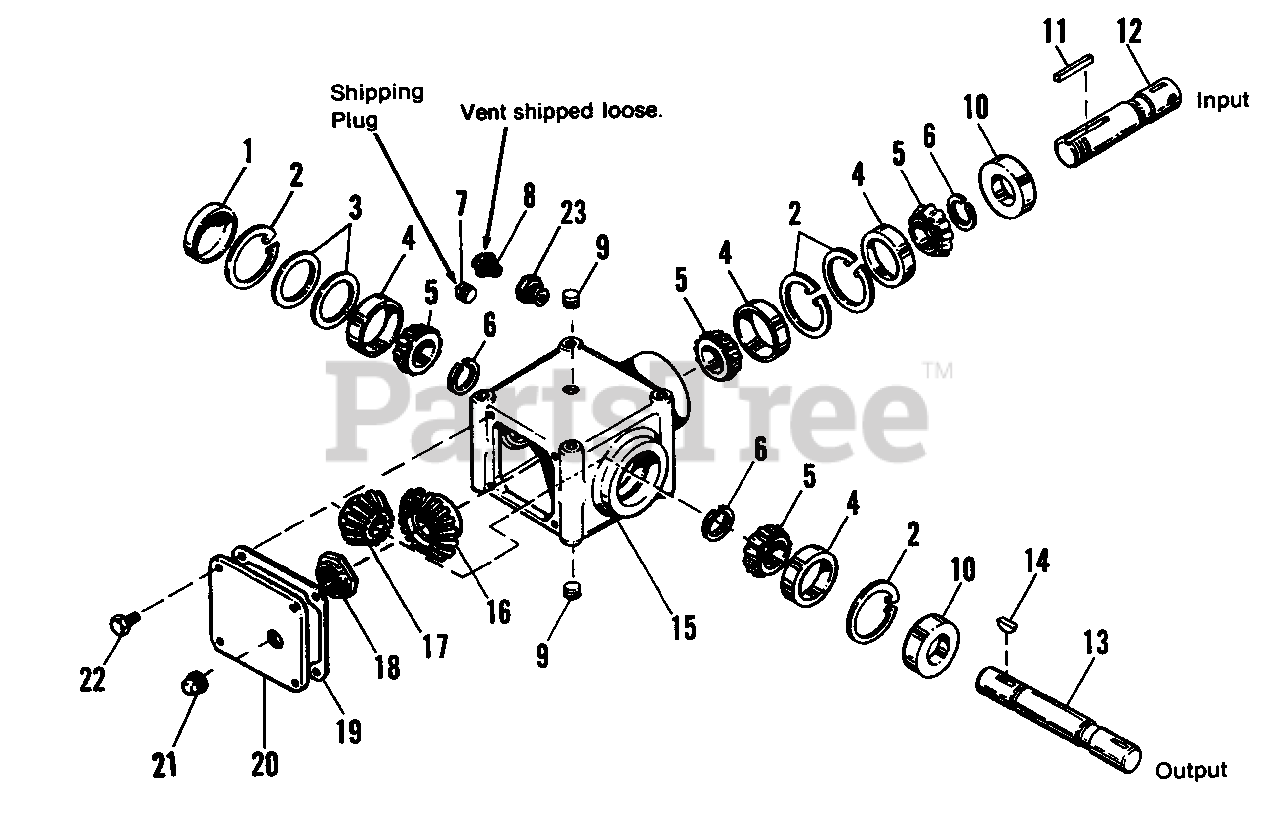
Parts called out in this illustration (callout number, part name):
1	CAP, Bevel Gear Box
2	SNAP RING
3	SHIM, Bearing
4	CUP, Cone Bearing
5	BEARING, Cone
7	PLUG, 1/8-27 NPT
8	PLUG, Vent, 1/8-27 NPT
9	PLUG, 3/8-18 NPT
11	KEY, Sq., 1/4 x 1/4 x 3/4
12	SHAFT, Input
13	SHAFT, Output
14	KEY, Woodruff, #9 (606) Hard
15	HOUSING, Bevel Gear
16	GEAR, Bevel,24 Teeth
17	GEAR, Pinion, 16 Teeth
18	NUT, Stake, 1-18
19	GASKET, Cover
20	COVER, Bevel Gear Box
21	PLUG, Level, 1/4-18
22	CAPSCREW, 5/16-18 x 5/8
23	REDUCER, 1/8-1/4
